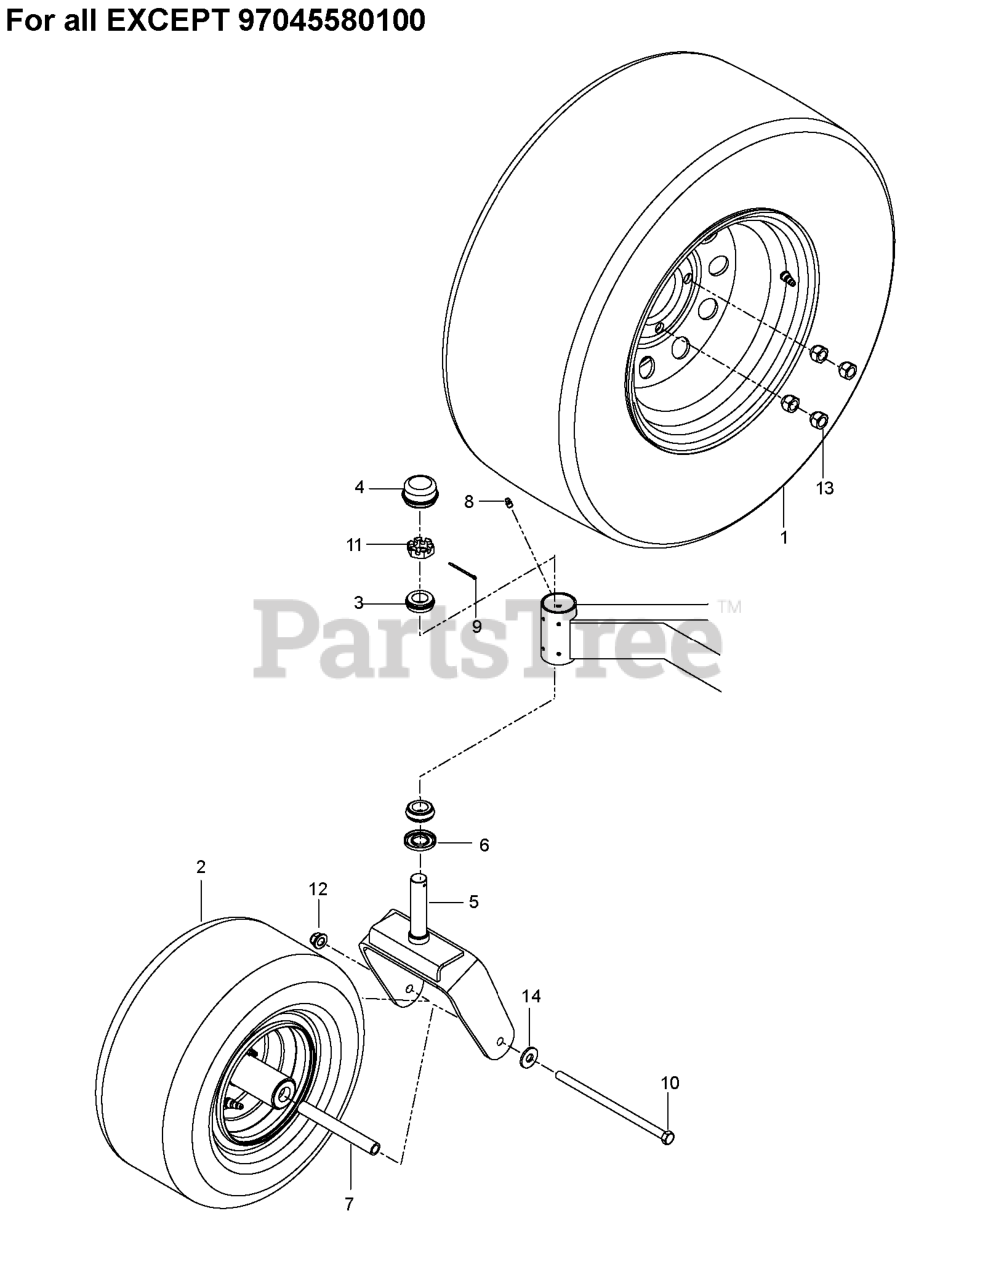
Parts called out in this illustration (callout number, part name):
1	WHEEL.ASSEM.22X10-10.SILVE.ZTR
2	TIRE.ASSEM.CASTER.13X6.5-6.SIL
3	TAPERED ROLLER BRG
4	GREASE CAP
5	FORK.CASTER.ASM.PNT.668
7	SPACER, PIVOT
9	COTTER PIN 1/8 X 2
10	HEX SCREW 1/2-13 X 9.5 GR5
11	NUT 1"C HEX SLOTTED
12	NUT.LK.W/WSH.1/2.
12	NUT, 1/2-13 HEX FLG NYLOC ZD
13	NUT.1/2-20.UNF-2B.GR.8.YL
14	WASHER.9/16 X 1 3/8 X 12 GA.
